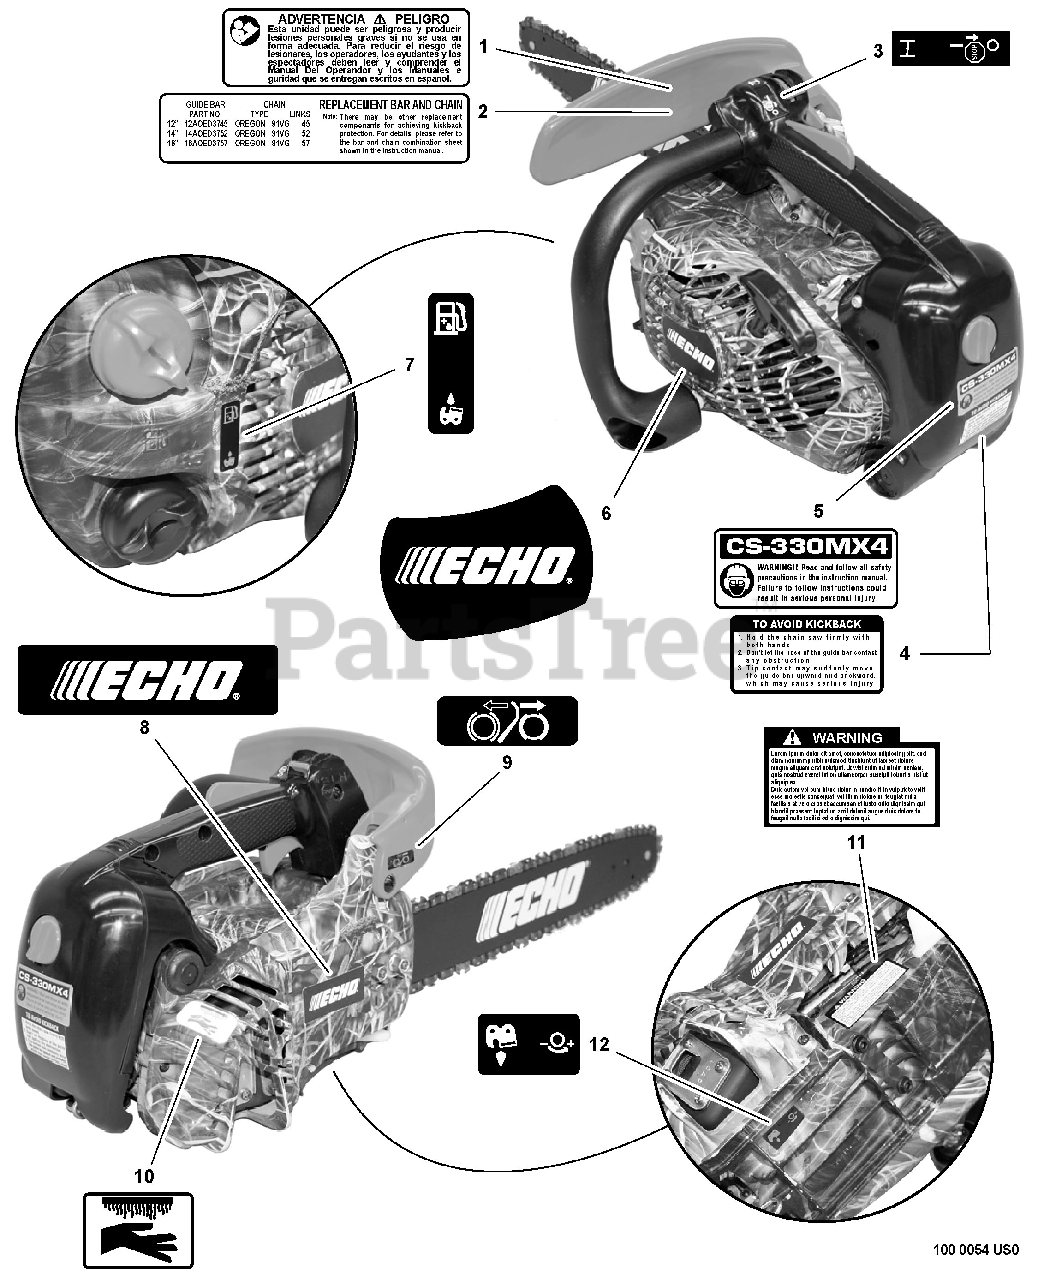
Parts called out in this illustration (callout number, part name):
1	LABEL - CAUTION -- SPANISH
2	LABEL - BAR & CHAIN
3	LABEL - STOP
4	LABEL - KICK BACK
5	LABEL - MODEL CS-330MX4
6	LABEL - ECHO
7	LABEL - FUEL MIX
8	LABEL - ECHO
9	LABEL - OPERATION
10	LABEL - HOT SURFACE
11	LABEL - CAUTION
12	LABEL- CHAIN OIL ADJUSTMENT
